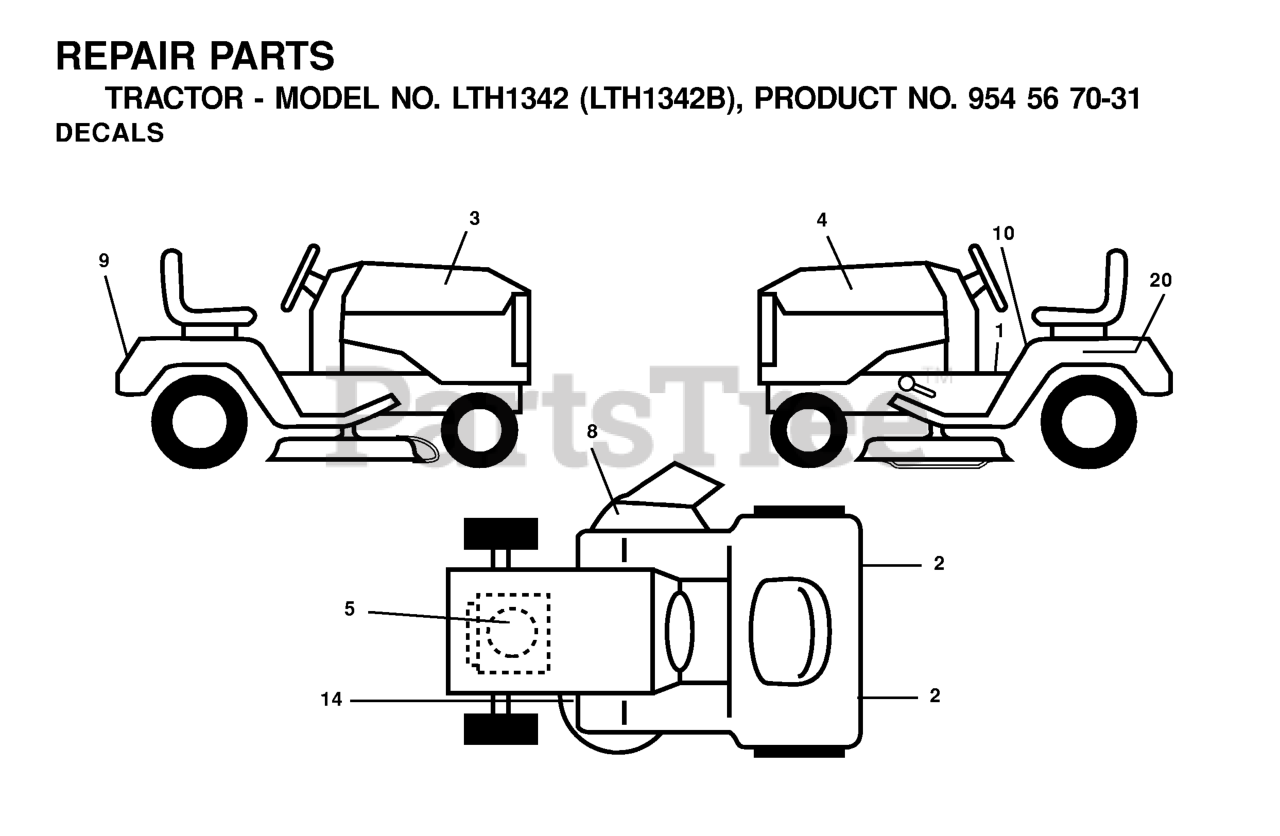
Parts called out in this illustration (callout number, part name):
2	REFLECTOR-TAIL YT
5	DECAL HP ENGINE
8	DECAL.WARN.KEEP.HAND.AWAY
9	DECAL, FENDER
10	DECAL FENDER DANGER
14	DECAL V BELT SCHEMATIC
20	DECAL BTRY SYMBOLS
